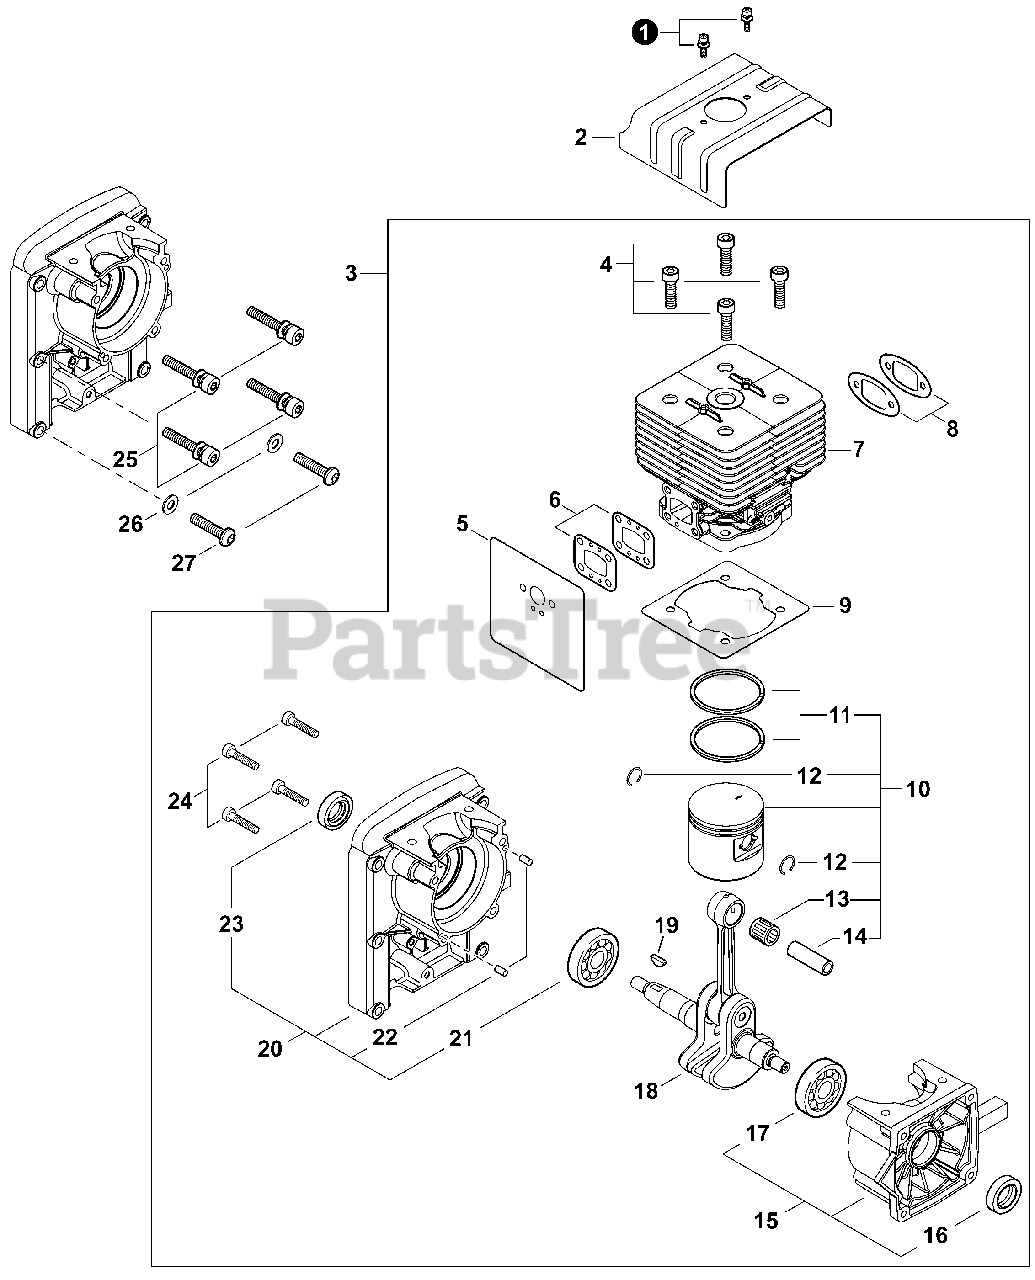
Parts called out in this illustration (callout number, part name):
1	BOLT M4×12
2	COVER, CYLINDER
3	SHORT BLOCK
4	BOLT 6×25
5	GASKET, INTAKE
6	GASKET, INTAKE
7	CYLINDER ASSY
8	GASKET, EXHAUST
9	GASKET, CYLINDER
10	PISTON KIT
11	RING, PISTON
12	RING, SNAP
13	BEARING, NEEDLE 12
14	PIN, PISTON 12
15	CRANKCASE ASSY, S
16	SEAL, OIL 21
17	BEARING, BALL 6302 C3
18	CRANKSHAFT
19	KEY, WOODRUFF 3×10
20	CRANKCASE ASSY, M
21	BEARING, BALL 6303 C3
22	PIN, LOCATING 4×8
23	SEAL, OIL 21
24	BOLT 5×30
25	BOLT, ADHESIVE M6×40
26	WASHER 6.5×13×1
27	BOLT, BUTTON 6×40
